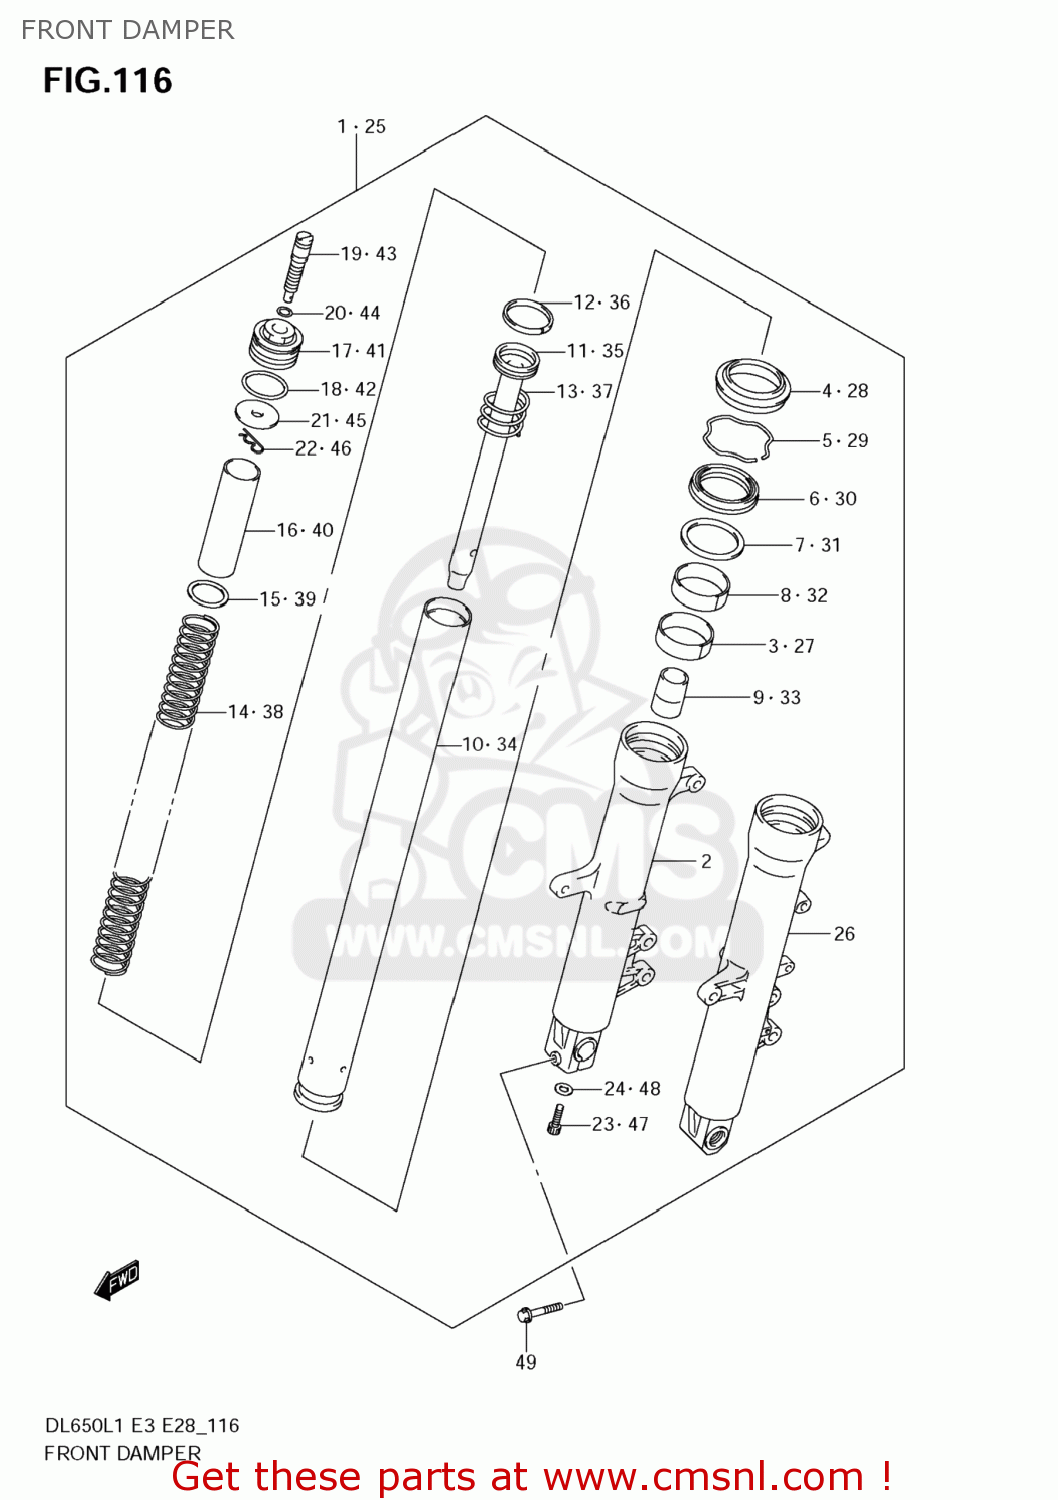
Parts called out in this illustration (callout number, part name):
1	DAMPER ASSY,FR FORK,R
2	TUBE,OUTER,R
3	BUSH,SLIDE
4	SEAL,DUST
5	CIRCLIP,FORK OIL SEAL
6	SEAL,OIL
7	SPACER,SEAL
8	BUSH,GUIDE
9	PIECE,OIL LOCK
10	TUBE,INNER
11	CYLINDER
12	RING,PISTON
13	SPRING,REBOUND
14	SPRING,FR
15	SEAT,SPRING LWR
16	COLLAR,SPRING
17	BOLT,FORK
18	O RING
19	ADJUSTER BOLT,SPRING
20	O RING
21	SEAT,SPRING
22	PIN,SEAT SPRING
23	BOLT(8X27)
24	GASKET (NAS)
25	DAMPER ASSY,FR FORK,L
26	TUBE,OUTER,L
27	BUSH,SLIDE
28	SEAL,DUST
29	CIRCLIP,FORK OIL SEAL
30	SEAL,OIL
31	SPACER,SEAL
32	BUSH,GUIDE
33	PIECE,OIL LOCK
34	TUBE,INNER
35	CYLINDER
36	RING,PISTON
37	SPRING,REBOUND
38	SPRING,FR
39	SEAT,SPRING LWR
40	COLLAR,SPRING
41	BOLT,FORK
42	O RING
43	ADJUSTER BOLT,SPRING
44	O RING
45	SEAT,SPRING
46	PIN,SEAT SPRING
47	BOLT(8X27)
48	GASKET (NAS)
49	BOLT(8X40)
